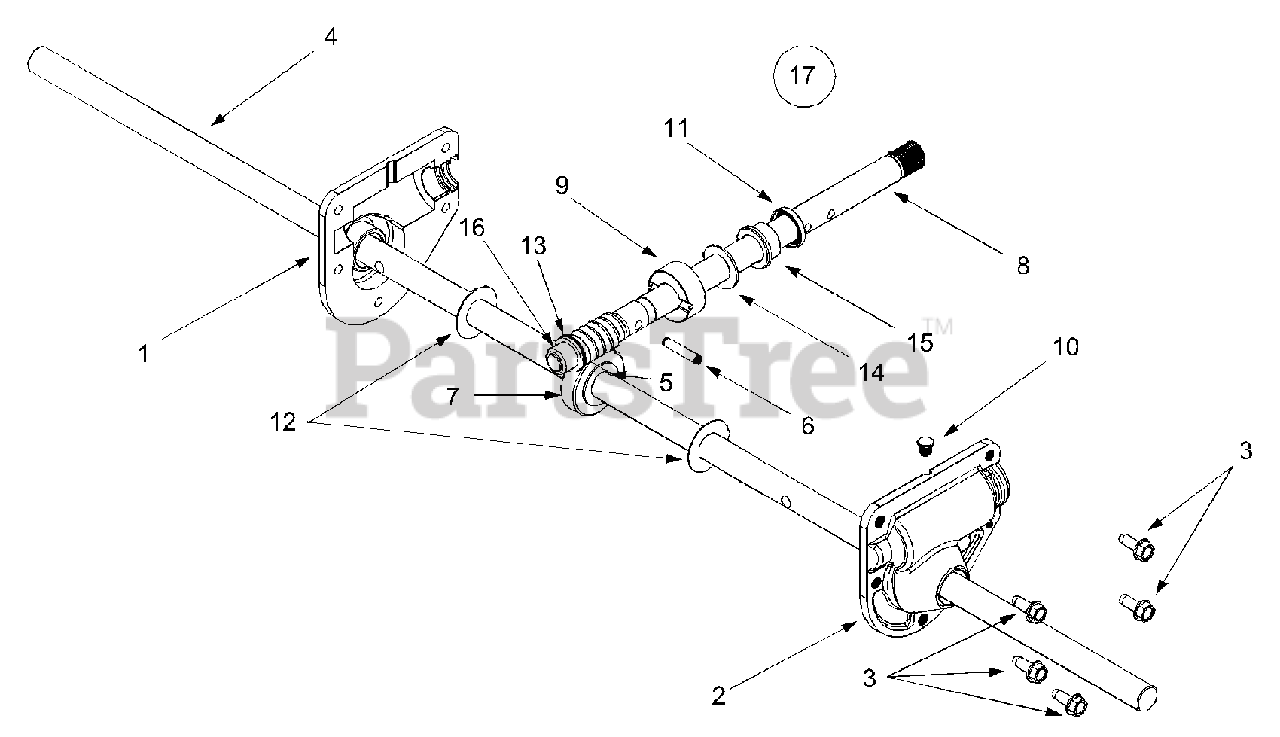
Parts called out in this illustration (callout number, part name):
1	RH Housing
2	LH Housing
3	Self Tapping Screw, 1/4-20 x .75
4	Spiral Axle, 28"
5	Hi-Pro Key, 3/16 x 5/8
6	Spring Spirol Pin, .25 x 1.25
7	Worm Gear, 20-tooth
8	Worm Shaft
9	Thrust Collar
10	Grease Plug
11	Grease Seal
12	Flat Washer, .76 x 1.5 x .030
13	Flat Washer, .508 x 1.0 x .020
14	Flat Washer, .76 x 1.5 x .060
15	Flange Bearing, .75 x 1.0 x .59
16	Flange Bearing, .503 ID x .75 OD
17	Gear Assembly Complete, 28"
